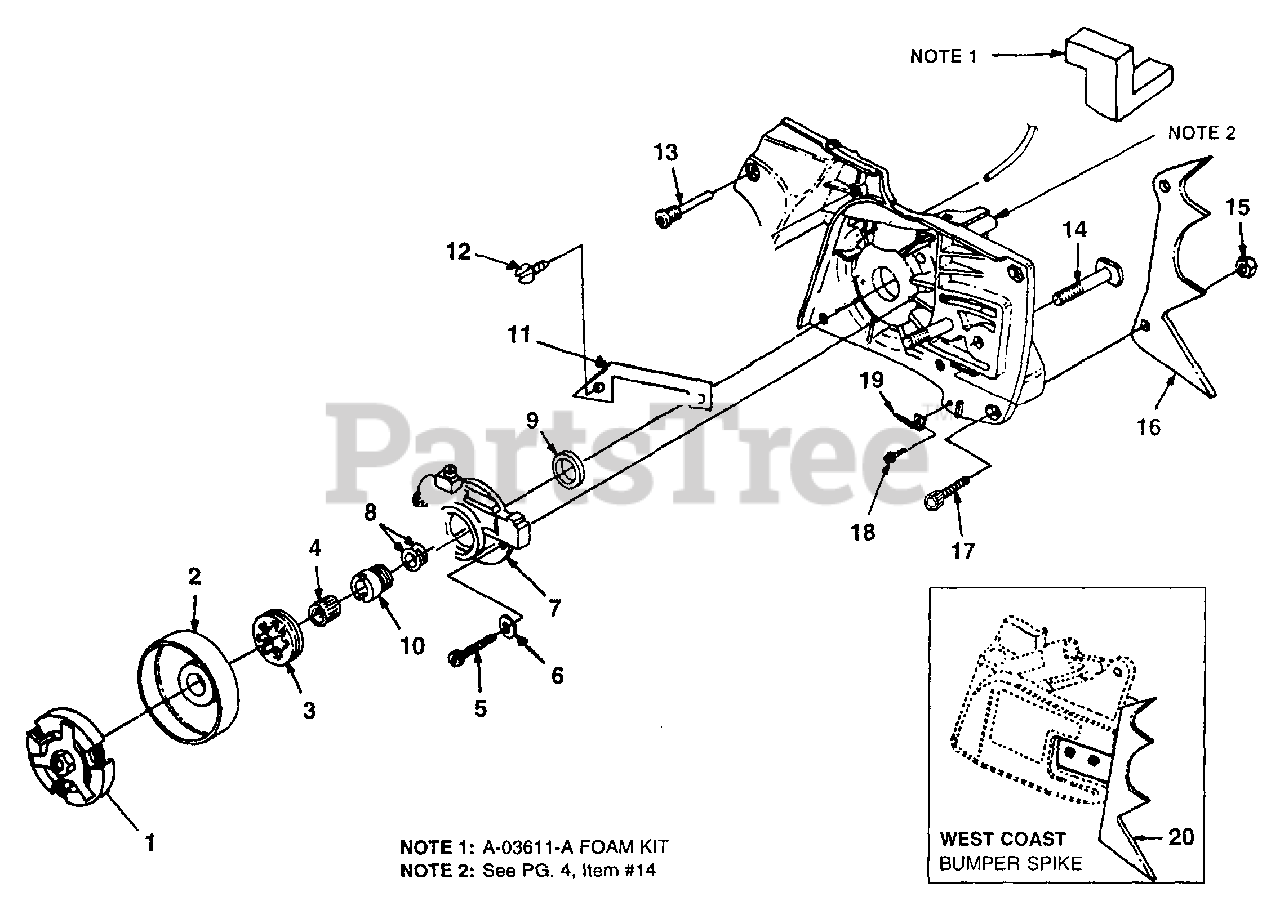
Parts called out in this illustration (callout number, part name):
1	CLUTCH
2	DRUM & HUB
3	SPROCKET (7T X 3/8P)
4	BEARING - Needle
5	SCREW - Cap Socket Hd. (10-24 X 7/8")
6	WASHER - Flat (010)
7	OIL PUMP
8	WASHER-Thrust
9	SEAL - Shaft
10	WORM & BEARING
11	SHIELD - Pump
12	SCREW - Slotted Hd. (8-32 X 1/4")
13	PIN - Isolator
14	BOLT - Guide Bar (3/8-16 X 2")
15	NUT - Hex (#12-24)
16	BUMPER SPIKE
17	SCREW - Socket Cap (12-24 X 5/8")
18	SCREW - Torx Hd. (10-24 X 1/2")
19	CHAIN - Stop
20	BUMPER SPIKE (West Coast)
